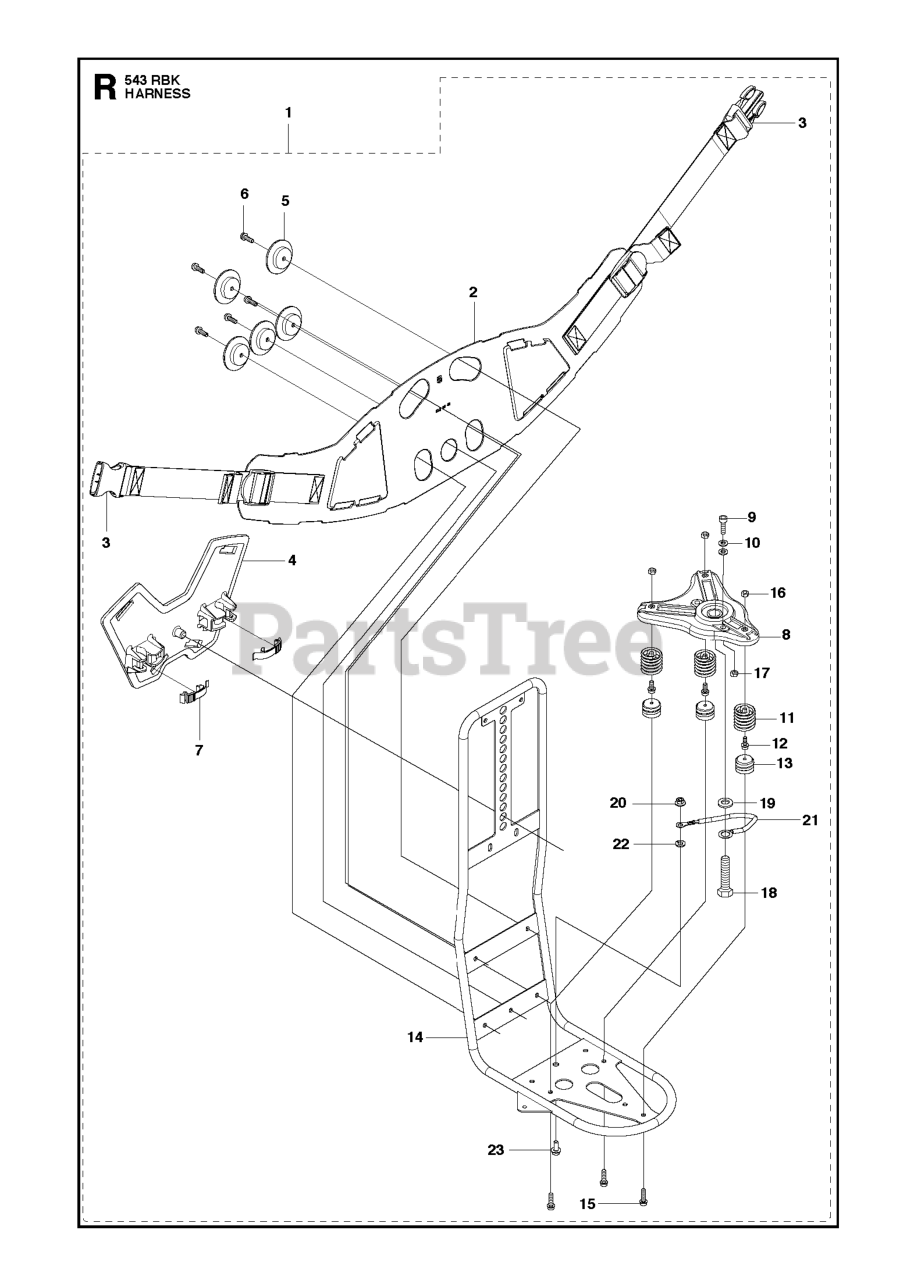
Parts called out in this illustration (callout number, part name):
6	SCREW IHSCFT
10	WASHER - M6
19	WASHER, M10 x 1.6
